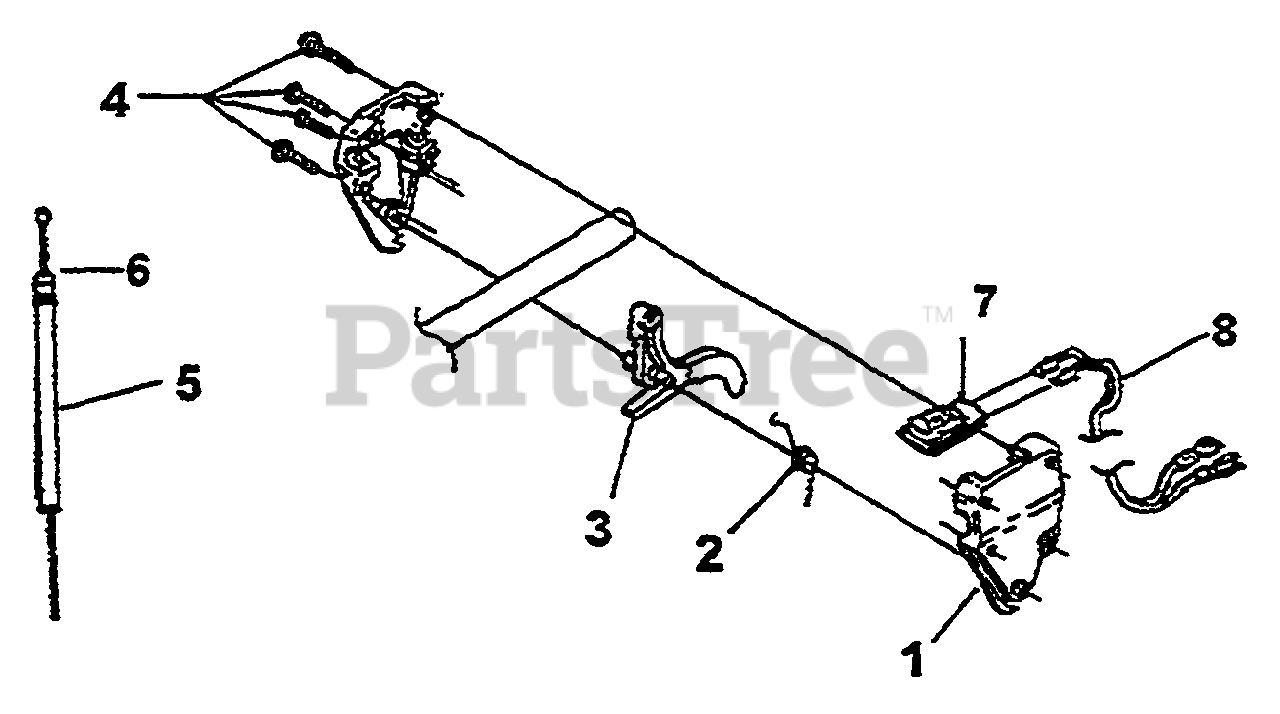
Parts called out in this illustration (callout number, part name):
1	THROTTLE ASSY.
2	SPRING, THROTTLE
3	LEVER, THROTTLE
4	SCREW
5	THROTTLE CABLE
7	SWITCH ASSY
8	WIRE HARNESS
